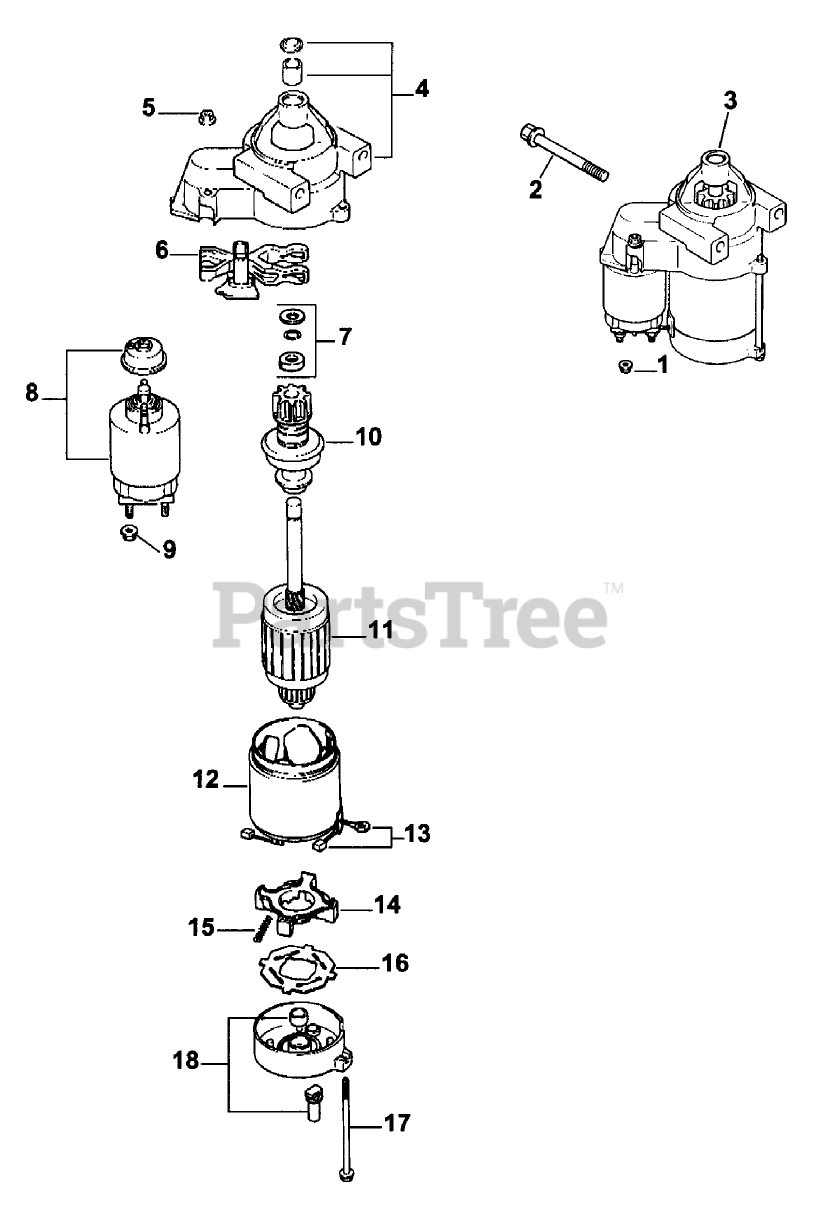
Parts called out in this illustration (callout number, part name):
1	Nut
2	Scew
3	Starter, solenoid shift (Includes 4-18)
4	Cap Drive End
5	Nut
6	Lever Starter Drive
7	Washer
8	Solenoid
9	Nut
10	Drive Pinion
11	Armature
12	Frame
13	Kit, brush (Includes 15)
14	Holder-Brush
15	Spring Brush
16	Insulator
17	Bolt
18	Cap-Commutator End
